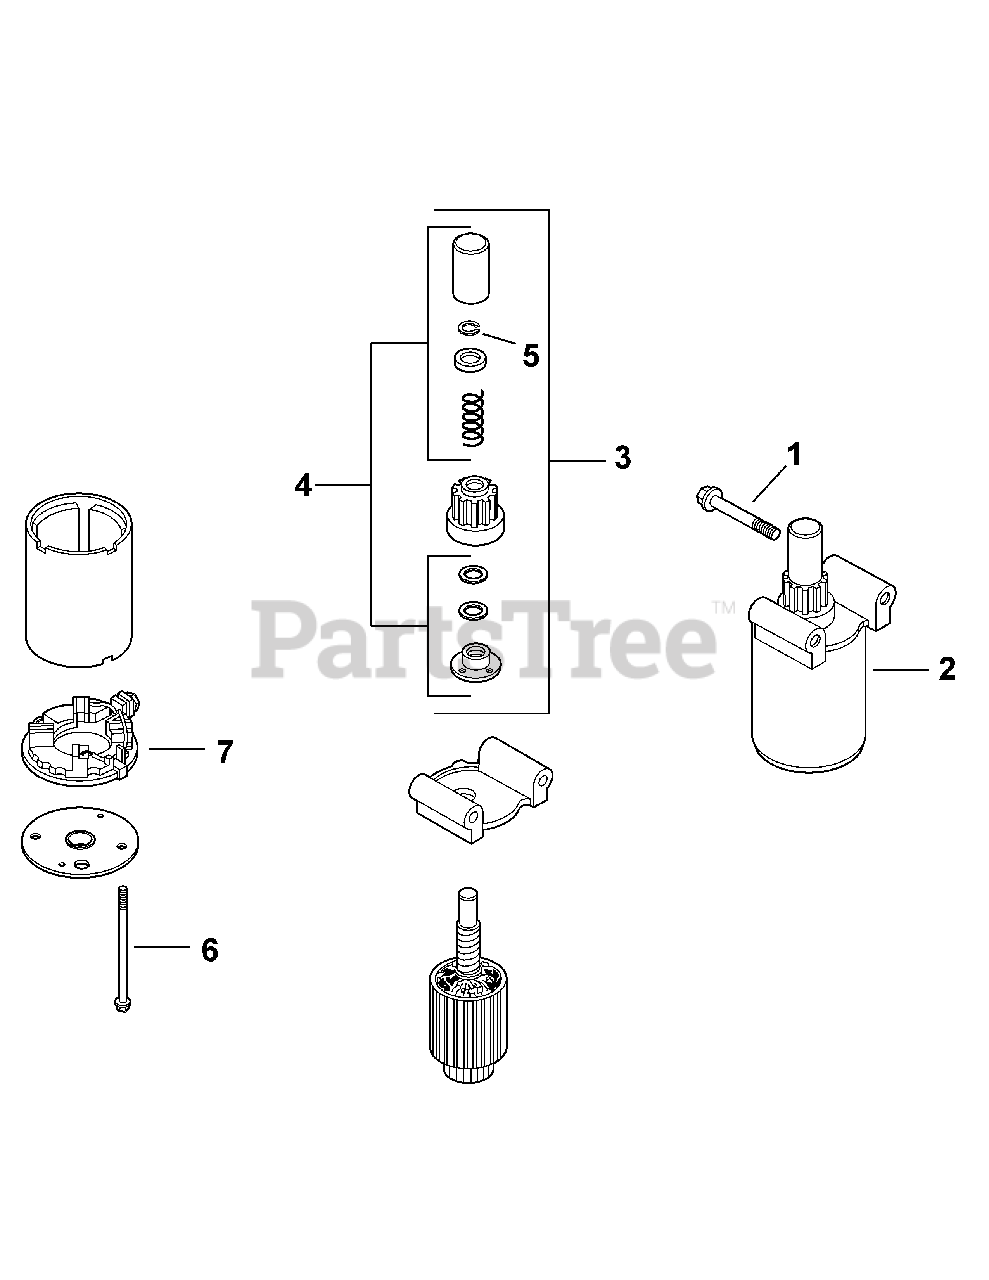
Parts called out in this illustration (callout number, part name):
1	Screw, Flange, M8 x 1.25 x 80
2	Starter Assembly
4	Kit, Drive Parts (Incl. Ref. 5)
5	Ring, Retaining Ring
7	Commutator, End Cap
